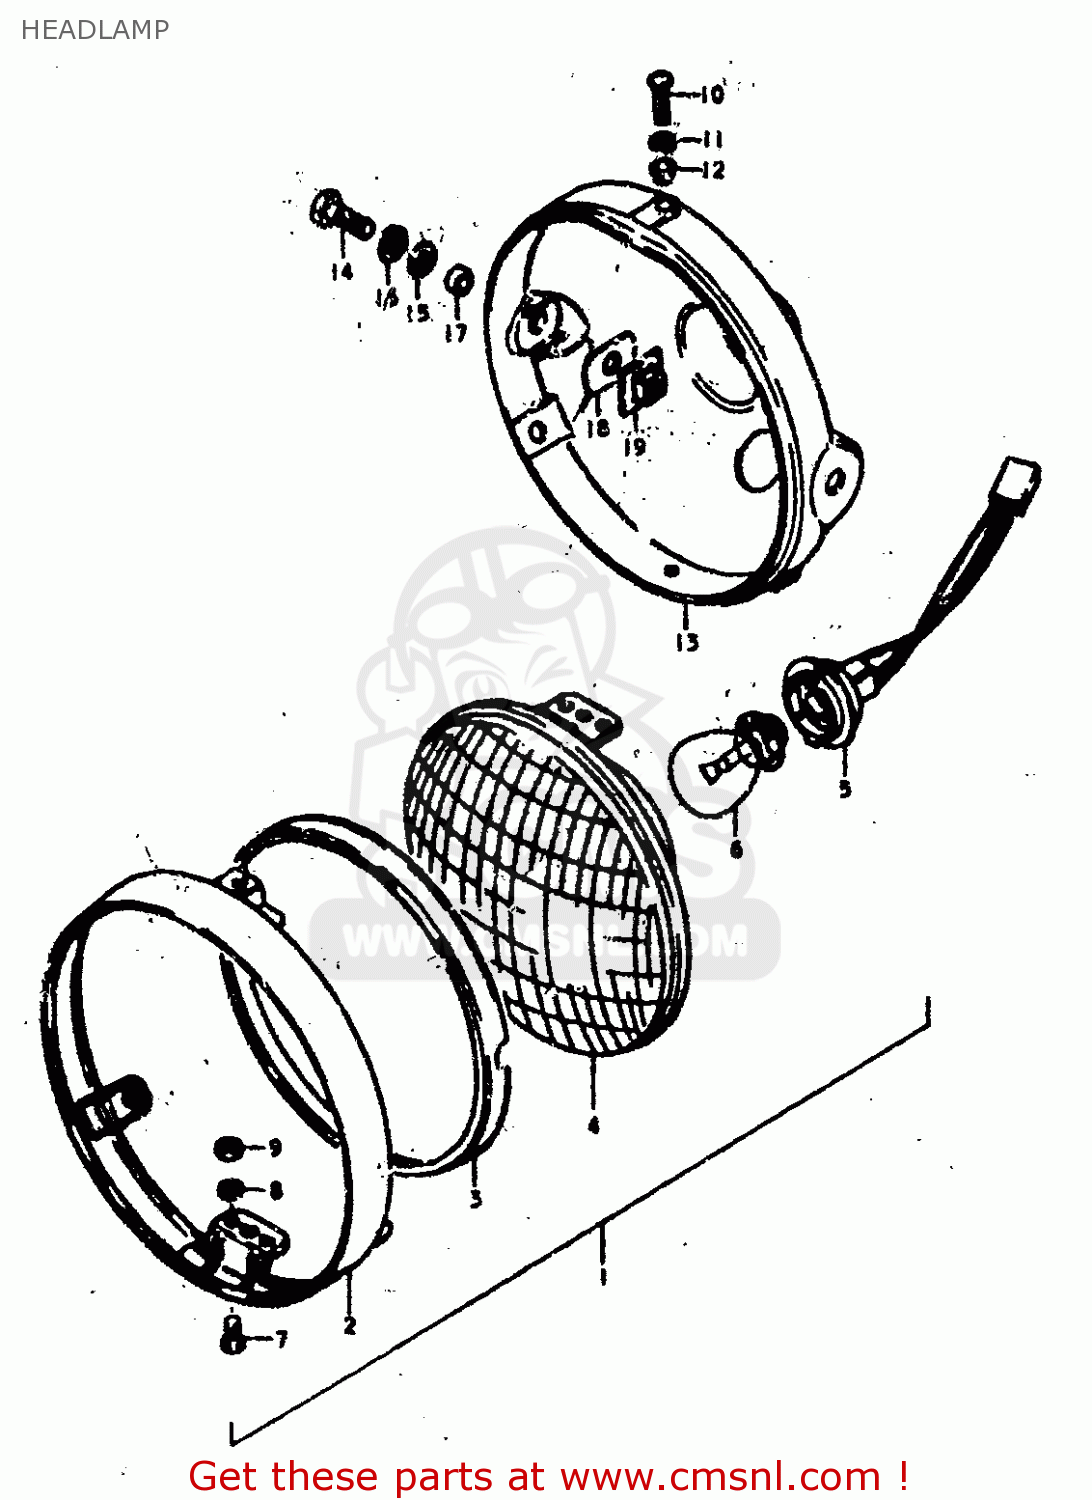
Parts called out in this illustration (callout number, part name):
1	HEADLAMP ASSY
2	RIM
3	RETAINER,HEADLAMP
4	UNIT
5	SOCKET
6	BULB
7	SCREW
8	LOCK WASHER
9	NUT
10	SCREW
11	WASHER,LOCK
12	WASHER
13	HOUSING,HEADLAMP(BLACK)
14	BOLT
15	WASHER
16	LOCK WASHER
17	SPACER (8.8X12X7)
18	CUSHION
19	PLATE,HEADLAMP HOUSING
